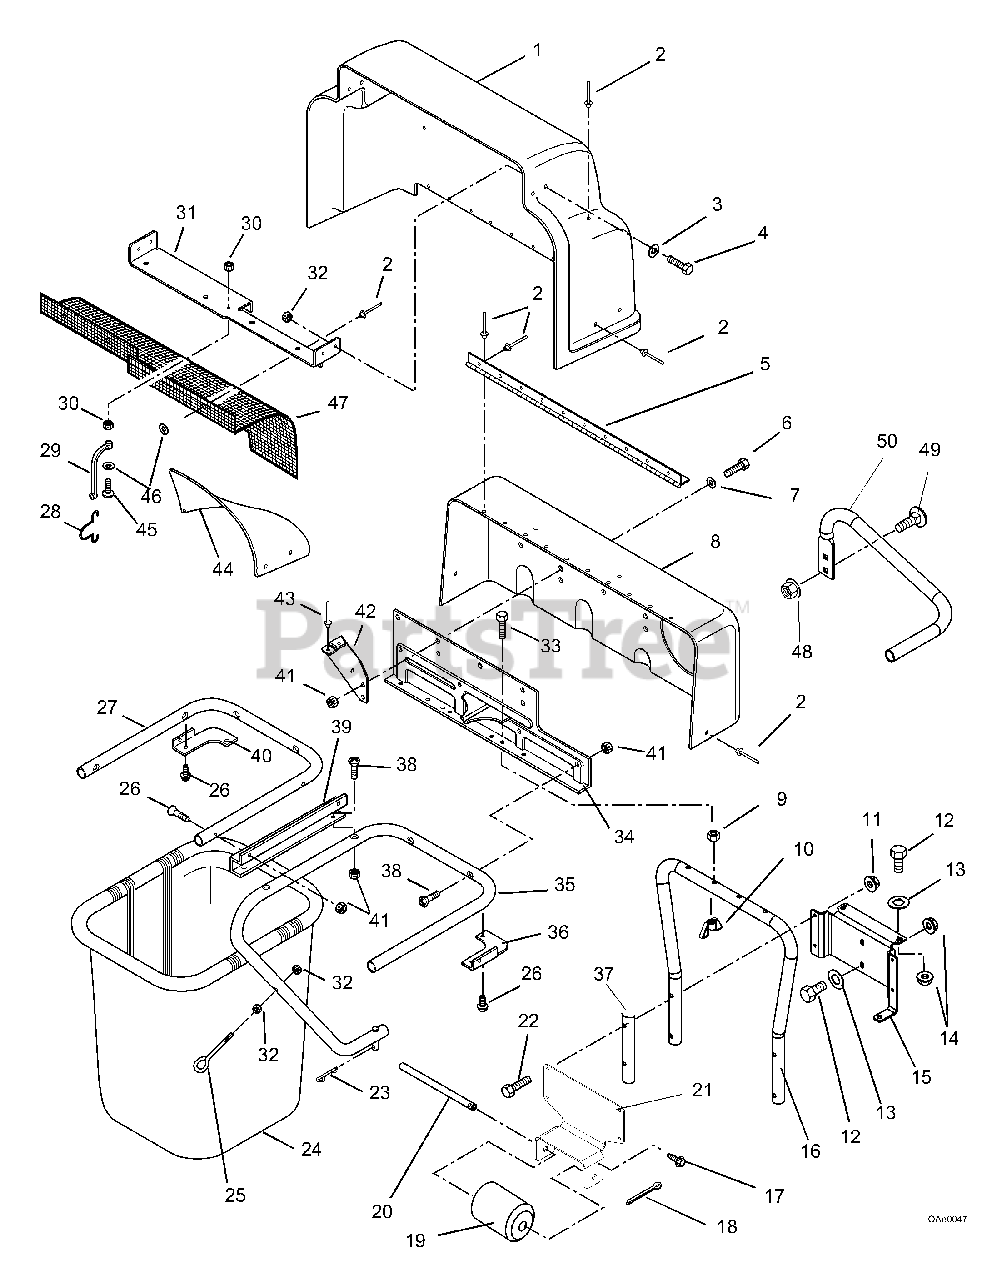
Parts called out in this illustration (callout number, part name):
1	HINGED COVER W/DECALS
2	RVT-POP .187X.402 DOME ST
3	@WSHR-FL-STL.281X.62X.065 YWZC
4	@BLT-HEX .25-20X.50 GR5 YWZC
6	@BLT-HEX .31-18X.75 GR5 YWZC
7	WSHR-FL-STL .328X.875X.062YWZC
8	STATIONARY COVER
9	@NUT-HEX .31-18 YWZC
10	NUT-NYLK WING .312-18 YWZC
11	@NUT-LK-TOP-FLG .31-18 YWZC
12	@BLT-HEX .38-16X1.00 GR5 YWZC
13	@WSHR-FL-STL.38X.875X.083 YWZC
14	@NUT-LK-TOP-FLG .38-16 YWZC
15	ASSY,MOUNT BRACKET
17	@SCR-TAP .25-20X.50 HWH TR YWZ
18	@PIN-CTR .25X2.00 YWZC
21	BRACKET, ROLLER
22	@BLT-HEX .31-18X1.50 GR5 YWZC
23	PIN-HAIR INT .08X.38X1.42 YWZC
24	GRASS BAGGER BASKET
25	EYEBOLT
26	@SCR-TAP .31-18X.50 HWH TR YWZ
27	CENTER TUBE
28	HOOK
29	BATTERY STRAP
30	@NUT-LK-NYL 10-24 W/INSRT YWZC
31	COVER BRACKET
32	@NUT-LK-CTR .25-20 YWZC
33	BLT-HEX .31-18X1.75 FLTHD YWZC
34	MOUNTING BRACKET
35	RIGHT TUBE
36	RH CORNER BRACKET
37	BRACE
38	SCR-MCH .31-18 X 1.50 YWZC
39	TUBE BRACKET
40	LH CORNER BRACKET
41	@NUT-LK-CTR .31-18 YWZC
42	BRACE
43	RVT-POP.187X.527 DOME ST
45	SCR-MCH 10-24X.88 SLRH YWZC
46	@WSHR-FL-STL.219X.50X.049 YWZC
47	SCREEN, BAGGER
48	@NUT-SPNLK-FLG .375-16 YWZC
49	@BLT-RDHDSQNK .38-16X.75 G5YZ
50	SUPPORT, 28" BAGGER TUBE
